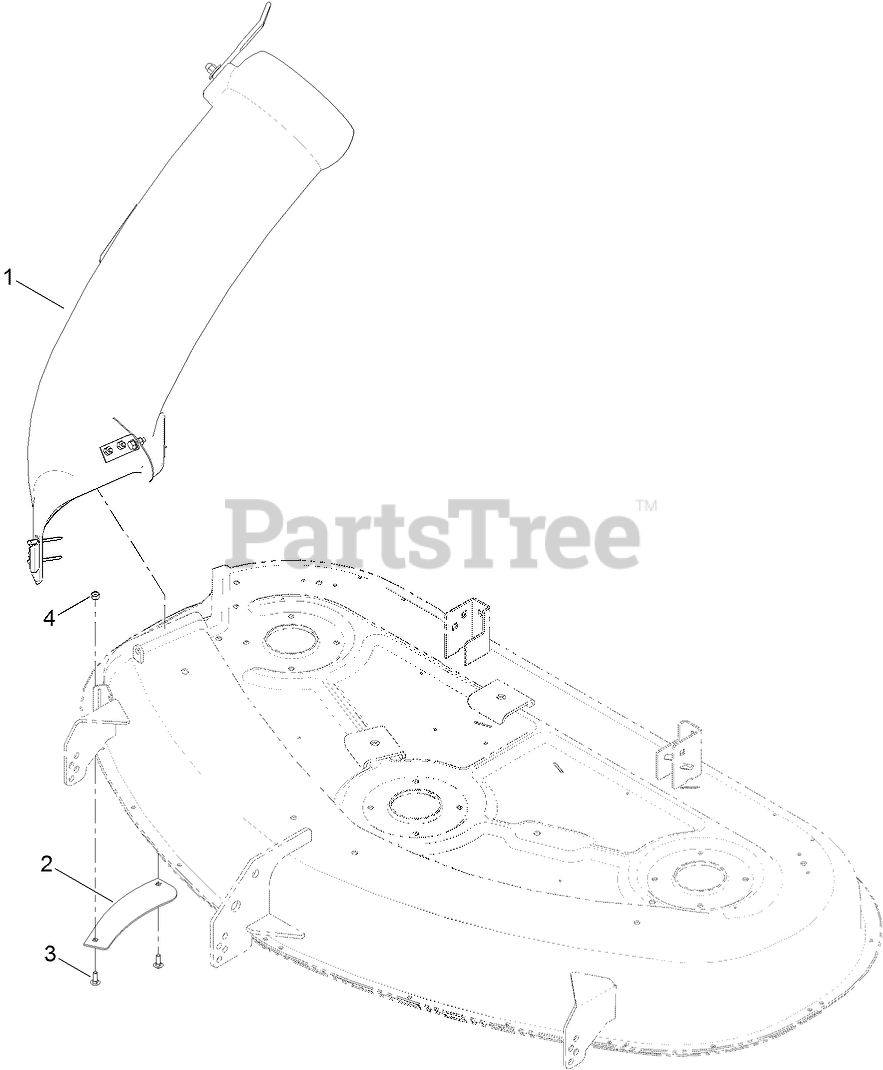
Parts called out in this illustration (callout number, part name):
1	50 INCH CHUTE ASM
2	BAFFLE-BLOWOUT
3	BOLT-CARR
4	NUT-LOCK, NI
